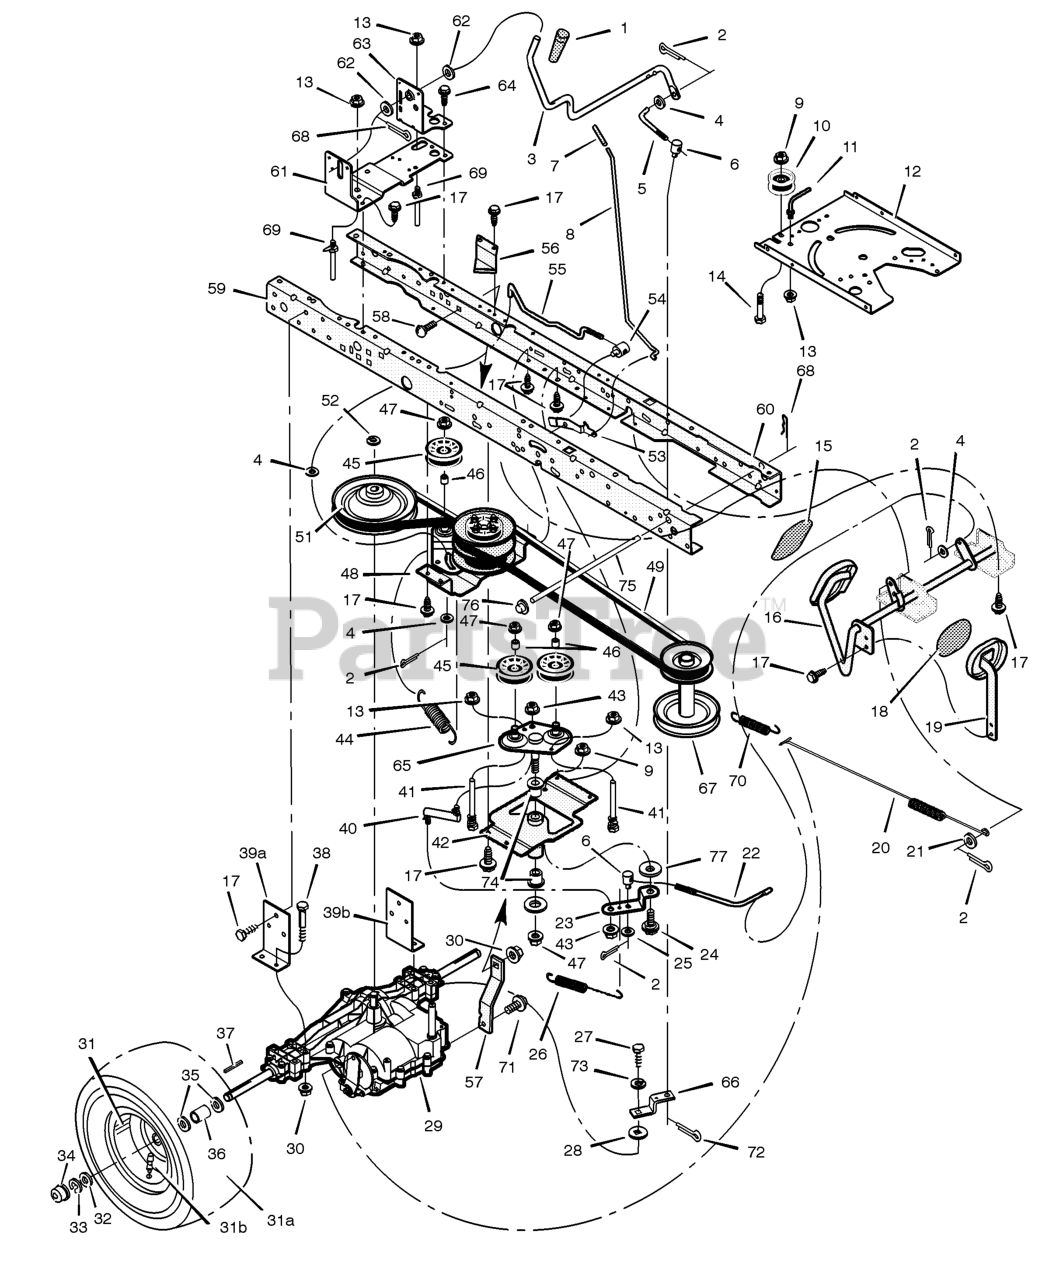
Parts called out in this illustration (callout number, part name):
1	Grip
2	Pin, Cotter
3	Lever, Shift
4	Washer
5	Link, Shifter
6	Nut, Adjuster
8	Rod, Parking Brake
9	Nut
10	Pulley, Idler
11	Guide, Belt
12	Plate, Steering
13	Nut
14	Bolt, Hex
15	Pad, Motion Drive
16	Assembly, Speed Control
17	Screw, Self Tapping
18	Pad, Brake Pedal
19	Assembly, Brake Pedal
20	Spring, Extension
21	Washer
22	Rod, Speed Control
23	Bellcrank
24	Bolt, Shoulder
26	Spring, Extension
27	Screw, Cap
29	Transaxle
30	Nut
31	Assembly, Wheel and Tire
31B	Stem, Valve
36	Spacer
37	Key, Square
38	Bolt, Hex
39A	Bracket, Right Transaxle
39B	Bracket, Left Transaxle
40	Rod, Secondary Control
41	Guide, Belt
42	Bracket, Front Frame
43	Nut, Lock
44	Spring, Extension
47	Nut
48	Assembly, Variator and Idler
49	Belt, Primary
50	Belt, Secondary
51	Pulley, Transaxle
52	Ring, Snap
53	Latch, Parking Brake
54	Nut, Adjusting
55	Rod, Clutch
56	Bracket, Brake
57	BRACKET, Torque Strap, LH
58	Screw
59	Rail, Right Frame
60	Rail, Left Frame
61	Bracket, Right Shift
62	Washer
63	Bracket, Shift Pivot
65	Assembly, Idler
66	Yoke, Shift
67	Pulley, Stack
68	Pin, Hair
69	Guide, Belt
70	Spring, Return
72	Pin, Hair
75	Rod, Belt Guide
76	Nut, Push-On
